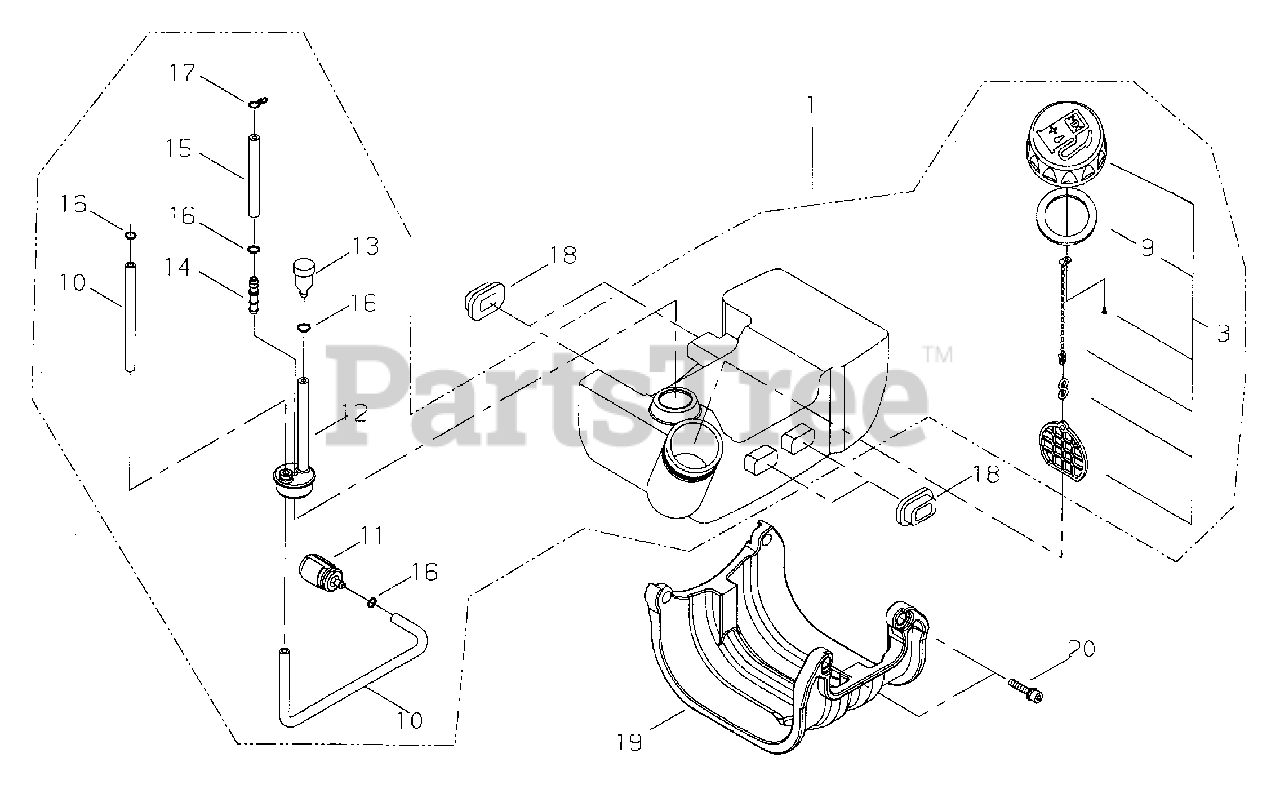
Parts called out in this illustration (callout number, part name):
1	FUEL TANK ASSY
3	CAP ASSY
5	GASKET, CAP
6	PIPE - FUEL
7	FILTER, FUEL
8	GROMMET
9	ELEMENT, BREATHER
10	CONNECTOR, PIPE
11	PIPE - RETURN
12	RING, RETAINING - 6
13	CLIP - SPRING
14	CUSHION, FUEL TANK
15	GUARD, FUEL TANK
16	SCREW - 5X20
